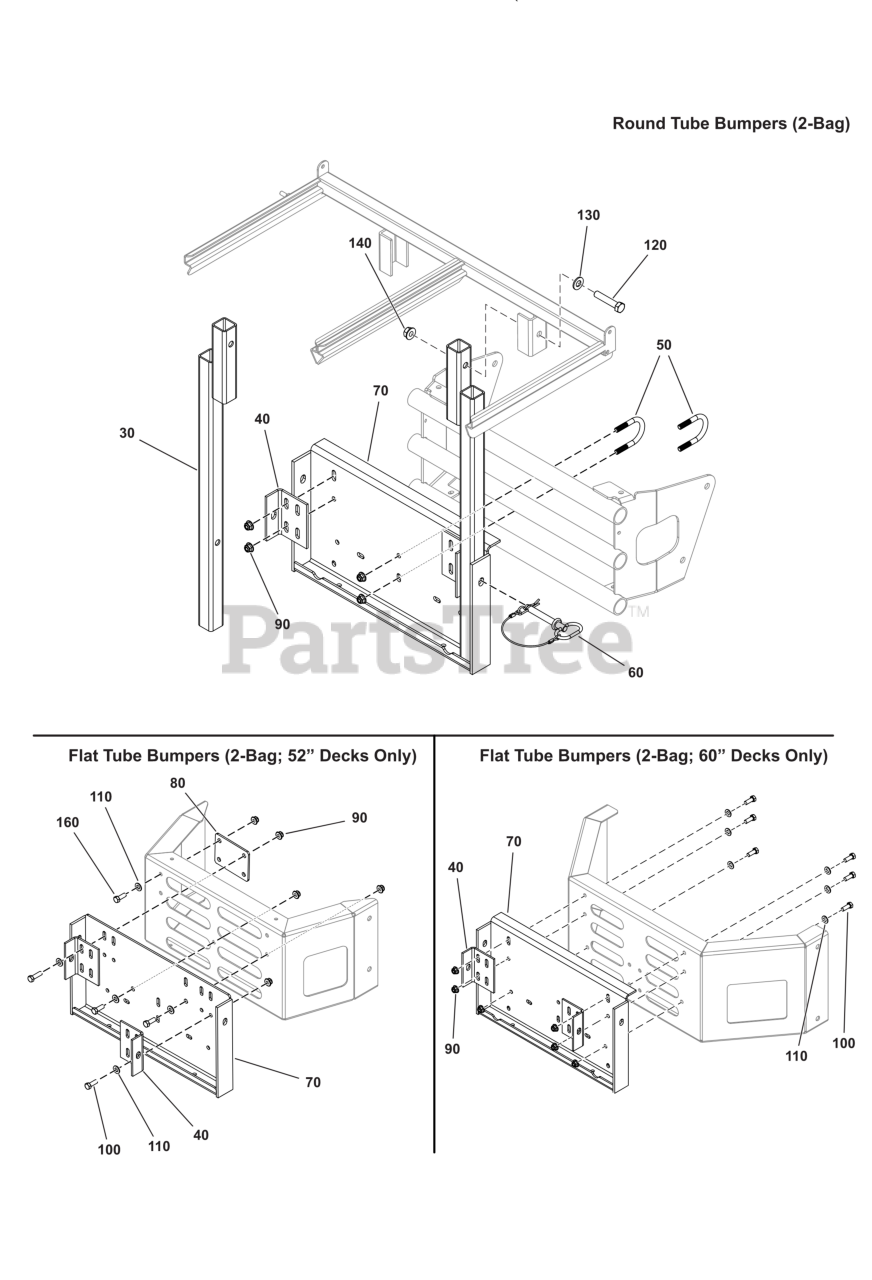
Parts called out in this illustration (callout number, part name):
40	BRACKET-MOUNTING
50	U-BOLT, 3/8 X 1-1/4
60	PIN, HITCH, .50 X 3.2
70	MOUNT, Bagger
90	NUT, 3/8-16 HEX NYLOCK
100	BOLT, 3/8-16 X 1" GD5
120	BOLT, 1/2-13 X 2-1/2
130	WASHER, 1/2" SAE
160	BOLT, 3/8-16 X 1-1/4"
